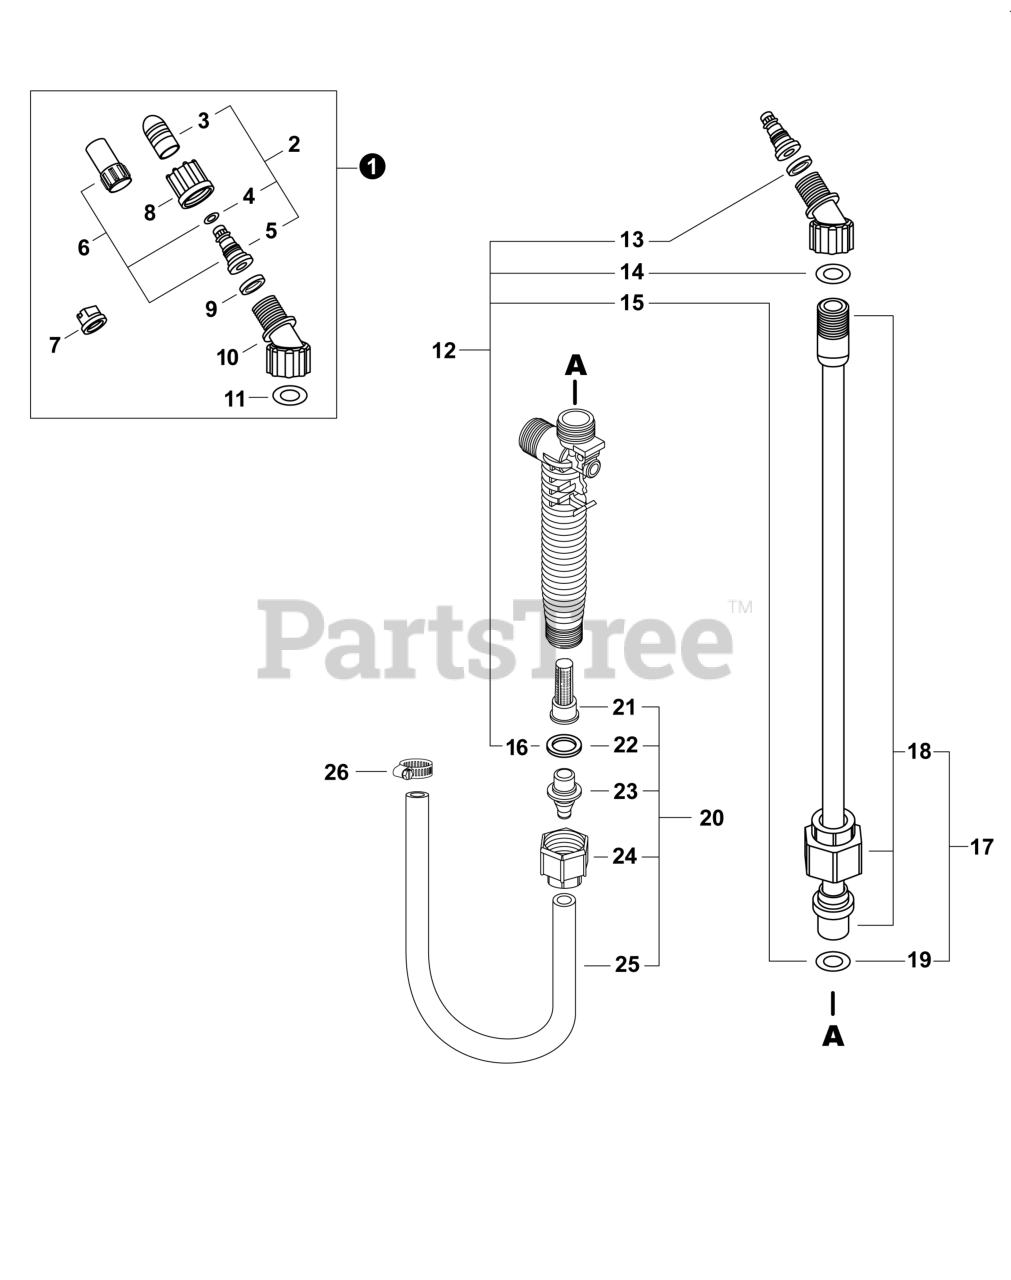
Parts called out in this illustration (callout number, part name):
1	NOZZLE KIT
2	NOZZLE KIT, BRASS
3	CAP, NOZZLE - BRASS
4	O-RING, NOZZLE
5	BODY, NOZZLE
6	NOZZLE KIT, PLASTIC
7	NOZZLE, FLAT FAN
8	NUT, NOZZLE
9	GASKET, NOZZLE
10	ELBOW, NOZZLE
11	O-RING, ELBOW
12	GASKET KIT, WAND
13	GASKET, NOZZLE
14	O-RING, ELBOW
15	O-RING, WAND 15 MM×3.5 MM
16	GASKET, ADAPTER
17	WAND ASSY, METAL
18	WAND, METAL
19	O-RING, WAND 15 MM×3.5 MM
20	HOSE KIT
21	FILTER, SPRAY GUN
22	GASKET, ADAPTER
23	ADAPTER, HOSE - BLACK
24	NUT, HOSE
25	HOSE, BLACK 1210 MM
26	CLAMP, HOSE
